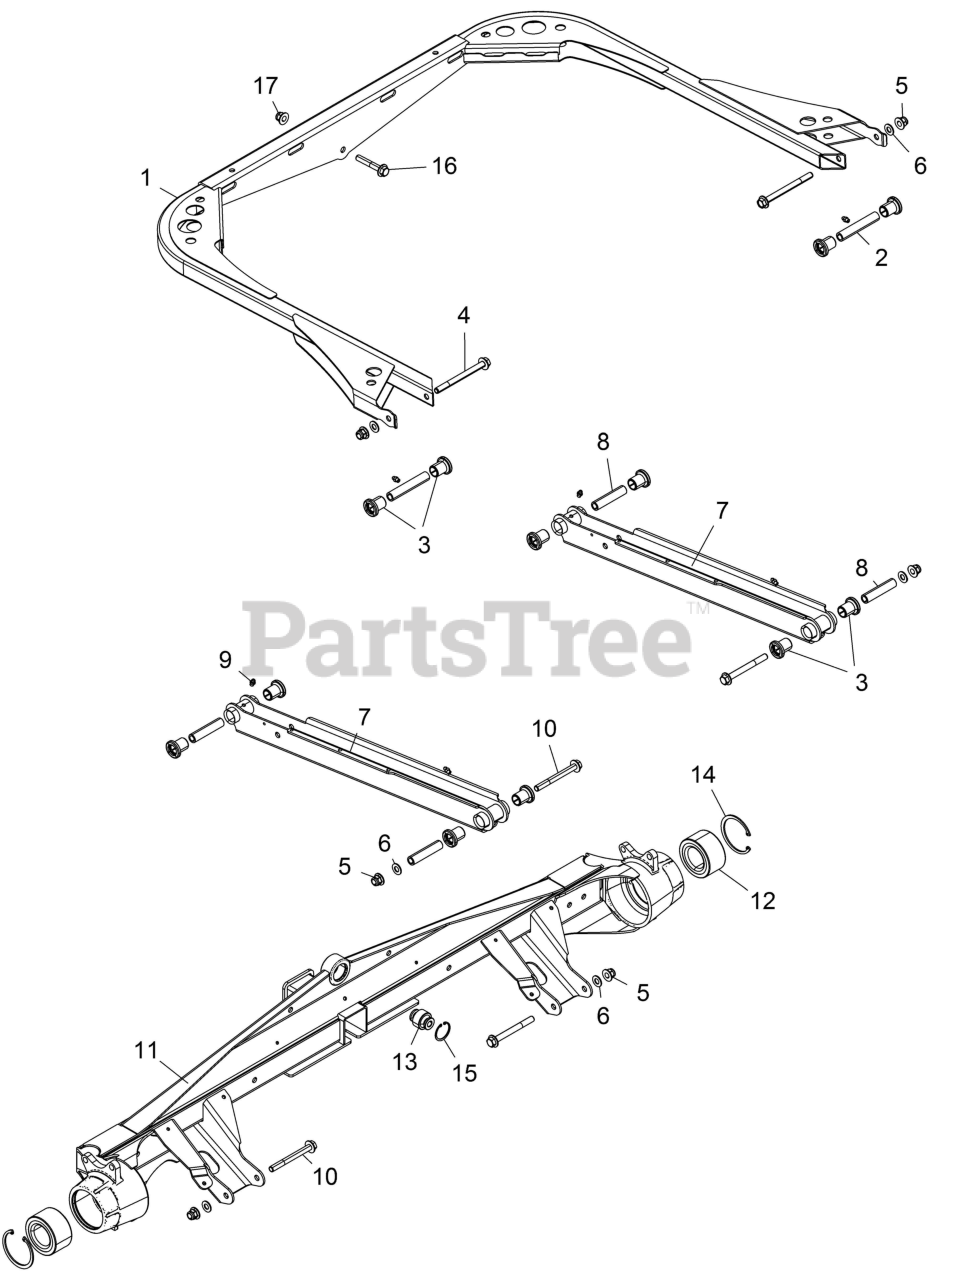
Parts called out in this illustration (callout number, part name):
1	WELD-UPPER LINK,M.BLK
2	SHAFT-PIVOT,89.71MM,15.88OD
3	BUSHING-STANDARD,ORV
4	BOLT-M10X1.25X115,HXFLG-OLIVED
5	NUT-M10X1.25,FLG,NYLOC-OLIVE D
6	WASHER,3/8 FW
7	WELD-LOWER LINK,BLK
8	SHAFT-PIVOT,70.99MM,15.88OD
9	FITTING, LUBRICATION
10	SCR-HXFL-M10X1.25X95 10.9 ZOD
11	WELD-REAR AXLE,BLK
12	BEARING, WHEEL
13	BEARING-SPHERICAL LOWER 10MM
14	RING,RETAINING
15	RING-RETAINING,1.25 ID HSNG
16	SCR-HXFL-M10X1.5X65 10.9 RIE
17	NUT-M10X1.5 HFN NYLOC ZOD
